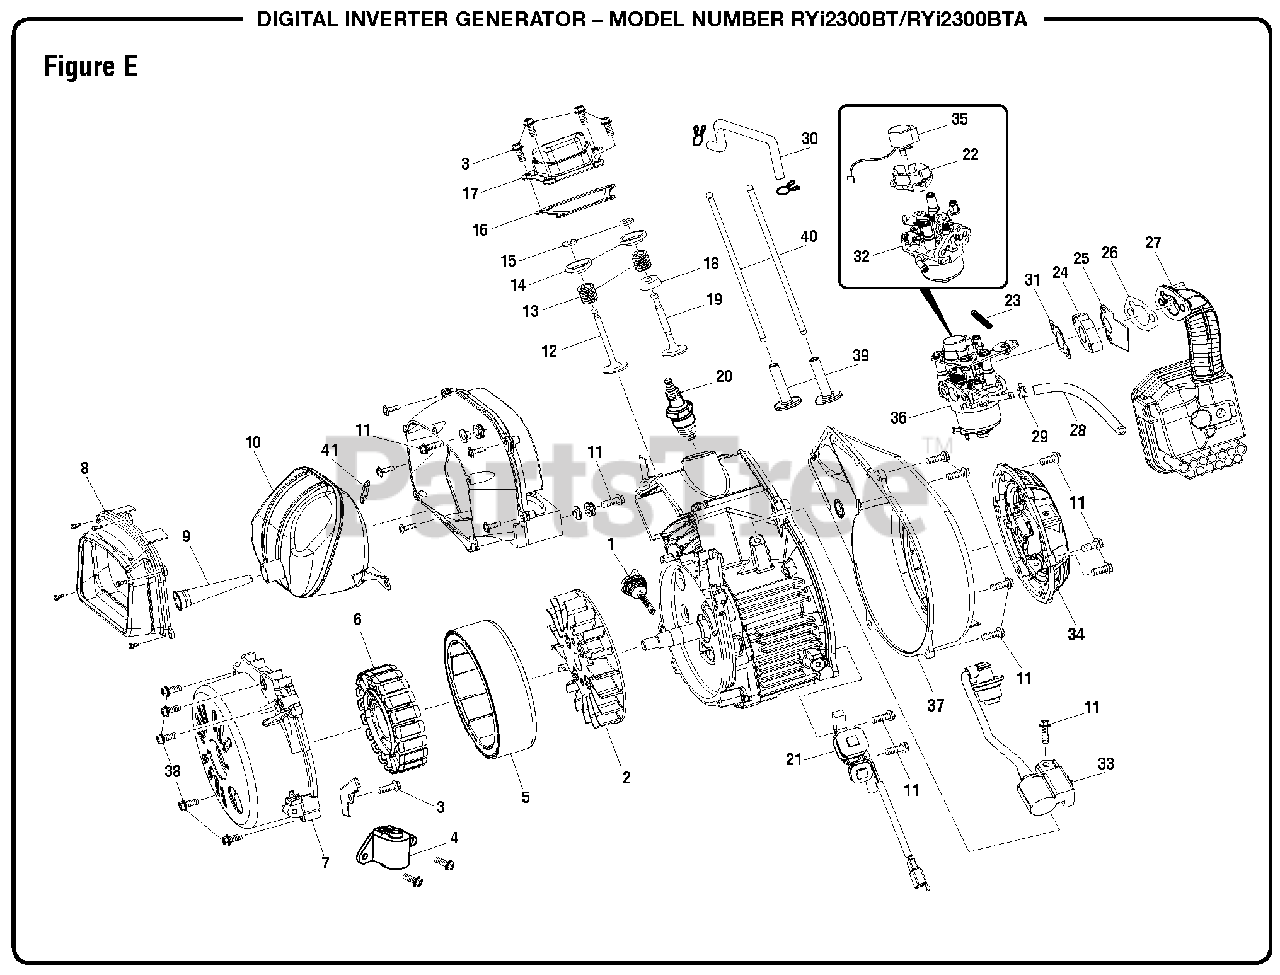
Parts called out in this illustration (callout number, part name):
1	Oil Dipstick
3	Bolt (M6 x 12 mm)
4	Low Oil Sensor
7	Alternator Cover
8	Muffler Heat Shield
9	Spark Arrestor
11	Bolt (M6 x 16 mm)
12	Exhaust Valve
13	Valve Spring
15	Valve Lock Clamp
16	Gasket (Over Head Cover)
17	Over Head Cover
18	Inlet Valve Spring Seat
19	Inlet Valve
20	Spark Plug
21	RPM Sensor
22	Governor Motor Housing
23	Compression Spring
24	Thermal Insulation Seat (Carburator)
25	Paper Gasket
26	Air Box Gasket
27	Air Filter Assembly
28	Fuel Hose (6 mm)
29	Fuel Line Clamp (7/16 in.)
30	Breather
31	Gasket (Connection Block)
32	Carburetor
33	Ignition Coil
34	Engine Recoil
35	Stepper Motor
36	Carburetor Assembly
37	Engine Cover
38	Bolt (M6 x 30 mm)
39	Lifter Valve
40	Pushing Rod
41	Gasket (Muffler)
